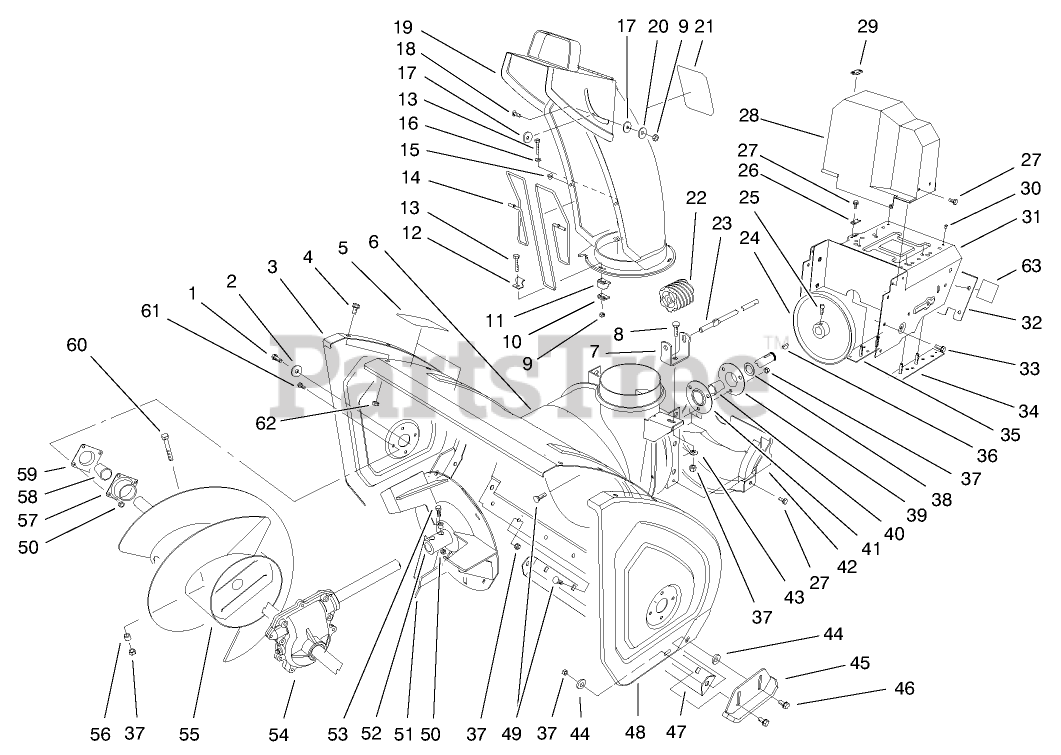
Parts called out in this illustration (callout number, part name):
1	SCREW-HH
2	WASHER
3	PLATE-SIDE, RH
4	SCREW-HHF
6	AUGER HOUSING ASM
6:2	DECAL-WARNING, AUGER
7	BRACKET-WORM, CHUTE
8	BOLT-CARR
9	NUT-LOCK, NI
10	PLATE-RETAINER, CHUTE
11	RETAINER-CHUTE
12	CLIP-GUARD, CHUTE
13	SCREW-HSH
14	GUARD-CHUTE
15	NUT-PUSH
16	WASHER-FLAT
17	WASHER-PLASTIC
19:2	DECAL-DANGER
19:2	DECAL - DANGER
20	WASHER-FLAT
22	GEAR-WORM
23	ROD-CHUTE, LOWER
25	SCREW-SET, SQH
26	RETAINER-CABLE
27	SCREW-HWH
28	COVER-BELT, UPPER
29	COVER-CABLE
30	RIVET-POP
31	ENGINE FRAME ASM
31:2	DECAL-WARNING
31:2	DECAL-ADJUSTMENT
32	COVER-FRAME, ENGINE
33	SCREW-HWHTF
34	LH FRAME PLATE ASM
35	RH FRAME PLATE ASM
36	KEY-WOODRUFF
37	NUT-LOCK, NI
38	WASHER-THRUST
39	FLANGE-CUP, BEARING
40	BEARING-BALL
41	FLANGE-CUP, BEARING
42	COVER-BELT, LOWER
43	WASHER-PLAIN
44	WASHER
45	SKID ASM
46	SCREW-HHF
47	SCRAPER BLADE ASM, 24"
48	PLATE-SIDE, LH
49	SCREW-CARR
50	NUT-LOCK, NI
52	SPACER
53	SCREW-HHF
54	AUGER GEARCASE ASM
55	RH AUGER ASM
56	SPACER-HUB, AUGER
57	BEARING-FLANGE, FRONT
58	BEARING
59	BEARING-FLANGE, REAR
60	SCREW-HH
61	SCREW-HH
62	NUT-LOCK, NI
63	DECAL
